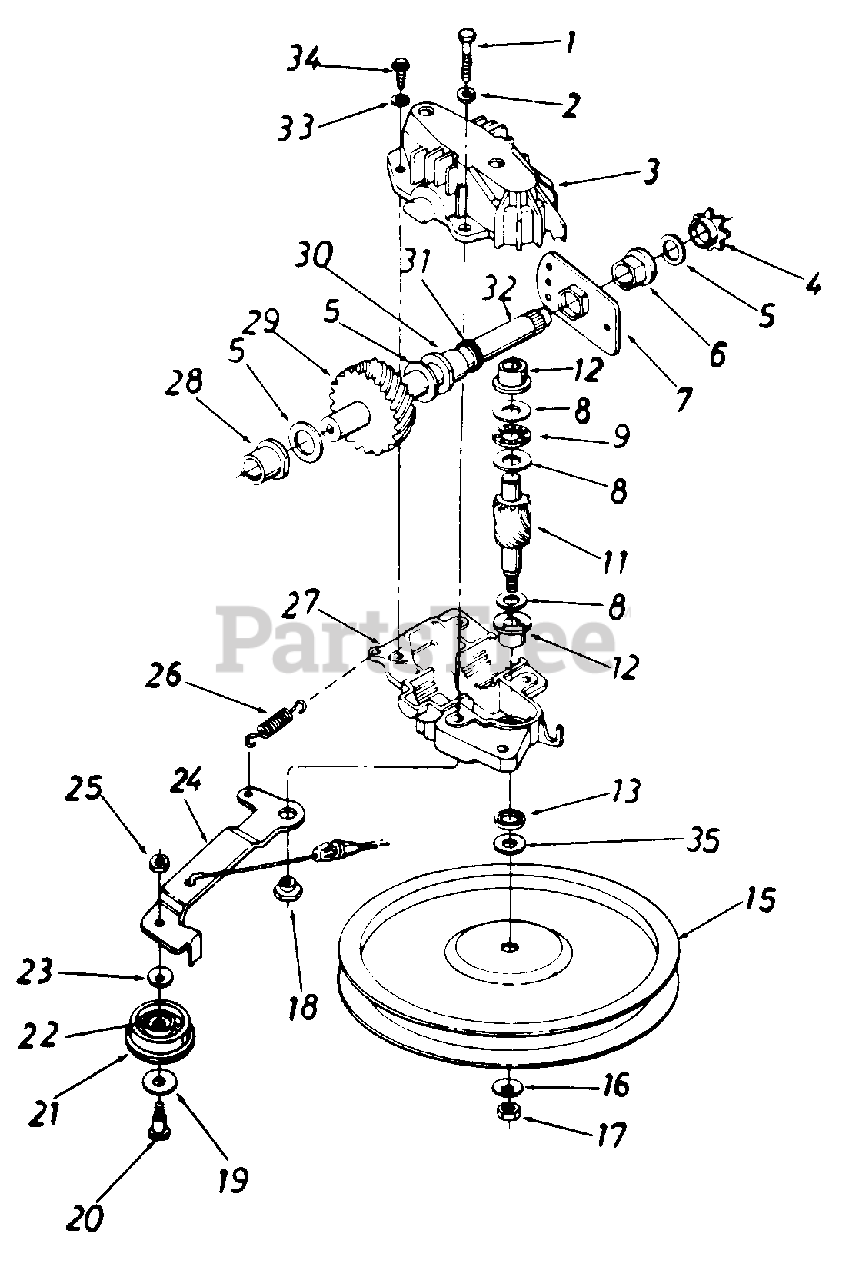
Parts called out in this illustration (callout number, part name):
1	Hex Bolt 1/4-20 x 1.25" Lg. w/Patch
2	L-Wash. 1/4" I.D.
3	Upper Hsg. Half
4	#48 Sprocket 7 Tooth x 1/2 Pitch
5	Fl-Wash. 5/8" I.D. x .030
6	Hex Flange Brg. .631" I.D.
8	Thrust Wash. .382" I.D. x .70" O.D.
9	Thrust Bearing .375" I.D. x .812" O.D.
11	11 Tooth Pinion Shaft
12	Flange Bearing
13	Oil Seal
15	Fl-Pulley 5.06" O.D.
16	Bell-Wash. .265" I.D. x 75"
17	Hex L-Nut 1/4-28 L.H. Thd.
18	Shld. Spacer.375" Dia. x 170
19	Fl-Wash. .390" I.D. x l.O"
20	Shld. Bolt .375" Dia. x .40"
21	FI-Idler Plastic 1.50" Dia
22	Needle Brg. .375" x .31
23	Bell-Wash. .265" I.D. x 75"
24	Idler Brk't. Ass'y.
25	Hex Patch L-Nut 1/4-28 Thd.
26	Extension Spring 1.12" Lg.
27	Lower Hsg. Half
28	Flange Bearing .566 Dia.
29	33 Tooth Helical Gear
30	Flange Bearing .629 Dia.
31	Oil Seal .625 Dia.
32	Gear Sprocket Shaft
33	L-Wash. #10 I.D.
34	Hex B-Tap Scr. #10 x .62"
35	Hex Washer .26" x .88"
